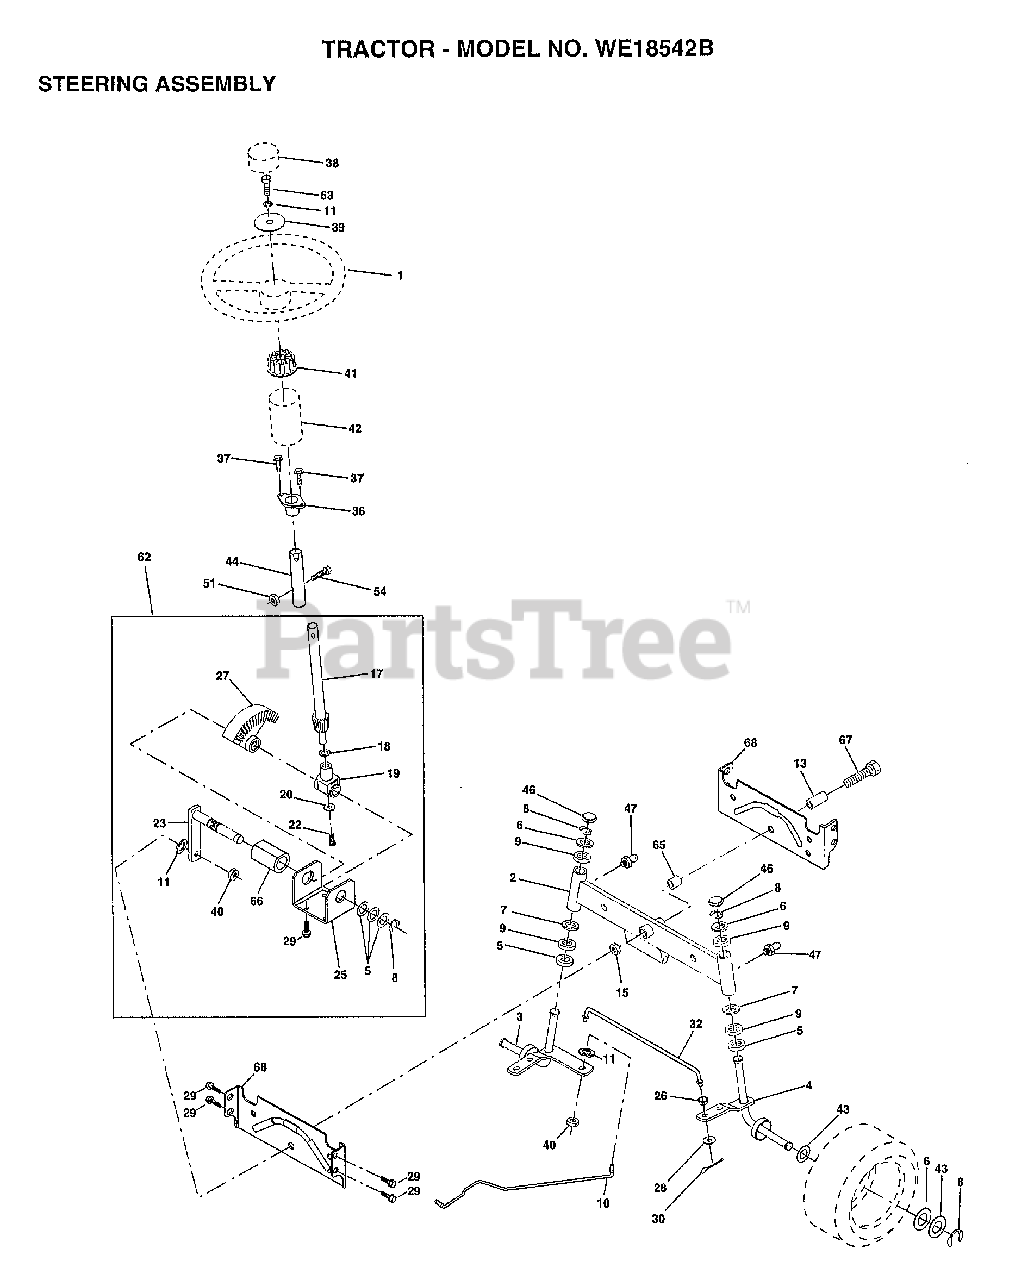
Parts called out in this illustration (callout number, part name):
1	WHEEL STR AYP BLK
2	AXLE ASM
3	SPINDLE.ASM.LH
4	"SPINDLE ASM,RH"
5	WASHER .T
6	WASHER
7	WASHER
8	RING
9	COL. SRTG. BEAR.
10	DRAGLINK-STAMPED
11	LOCKWASHER
13	BEARING AXLE
15	"NUT-LOC,FLANGE LT"
17	SHAFT ASM STEERIN
18	THRUST WASHER
19	SUPPORT.SHAFT
22	SCREW HEX SOC1/4-
25	BRKT-STEERING
26	BUSHING.DRAGLINK
27	GEAR SECTOR
28	WASHER
29	SCREW
30	COTTER PIN
32	TIE ROD
36	BUSHING.STEERING
37	"SCREW-TT,10-32 FL"
38	CAP STEER AYP
39	WASHER T
40	GRIPCO NUT
41	ADAPTER LT
42	BOOT.STEER.PL
43	WASHER
44	EXT SHAFT STEERIN
46	CAP
47	ZERK M
51	NUT
54	BOLT
62	KIT STEERING ASM
63	BOLT
65	SPACER AXLE
66	"BEARING-ARM,PITMA"
67	BOLT
68	BRACE AXLE
